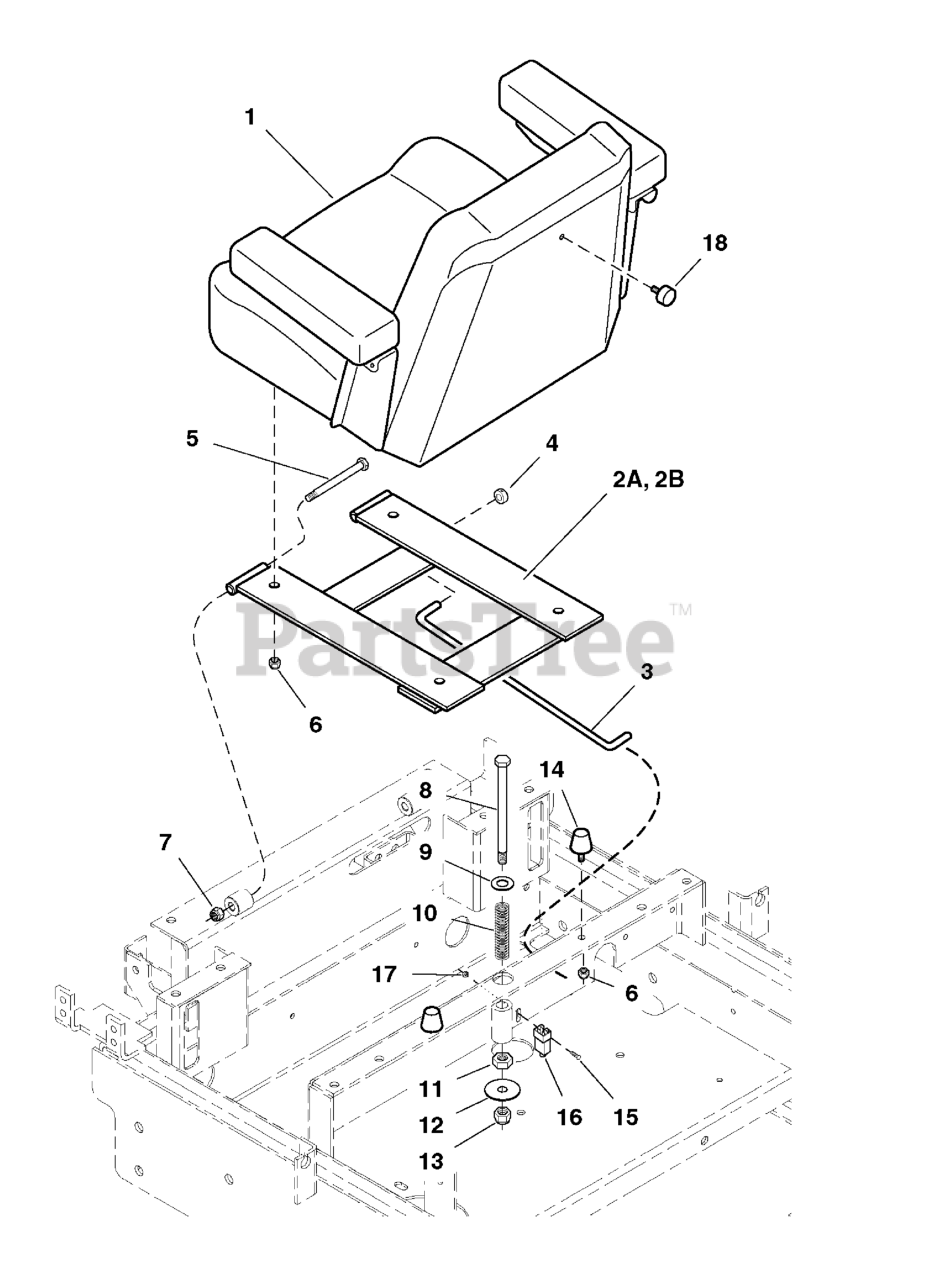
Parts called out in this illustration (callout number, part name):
1	SEAT, GRAY, NO LOGO, CMPT
1	SEAT BOTTOM (EVC 907)
1	CUSHION, Back, Gray
1	ARM REST, Black
1	SEAT ADJUSTER RAILS (Set)
2A	SEAT MOUNT
2B	SEAT MOUNT
3	SEAT STOP ROD
4	COLLAR, 5/16" Set
5	BOLT, 3/8-16 X 4" GD5 CZ
6	NUT, 5/16-18 Hex Nylon Lock
7	NUT, 3/8-16 HEX NYLON LOCK
8	BOLT, 1/2-13 x 6-1/2
9	WASHER, 1/2 SAE
10	SPRING, Compression
11	NUT, 1/2-13 Hex Jam
12	WASHER, Reinforcement
13	NUT, 1/2-13 HEX NYLON LOCK
14	RUBBER BUMPER
15	SCREW, #10-24 X 1 RS, CZ
16	SWITCH, Plunger, NO/NC
16	SWITCH, PLUNGER, N.O./N.C.
17	NUT, #10-24 Hex
18	RUBBER BUMPER
19	SPRING, EXTENSION, SEAT ADJUSTMENT (YEL OR BLK)
